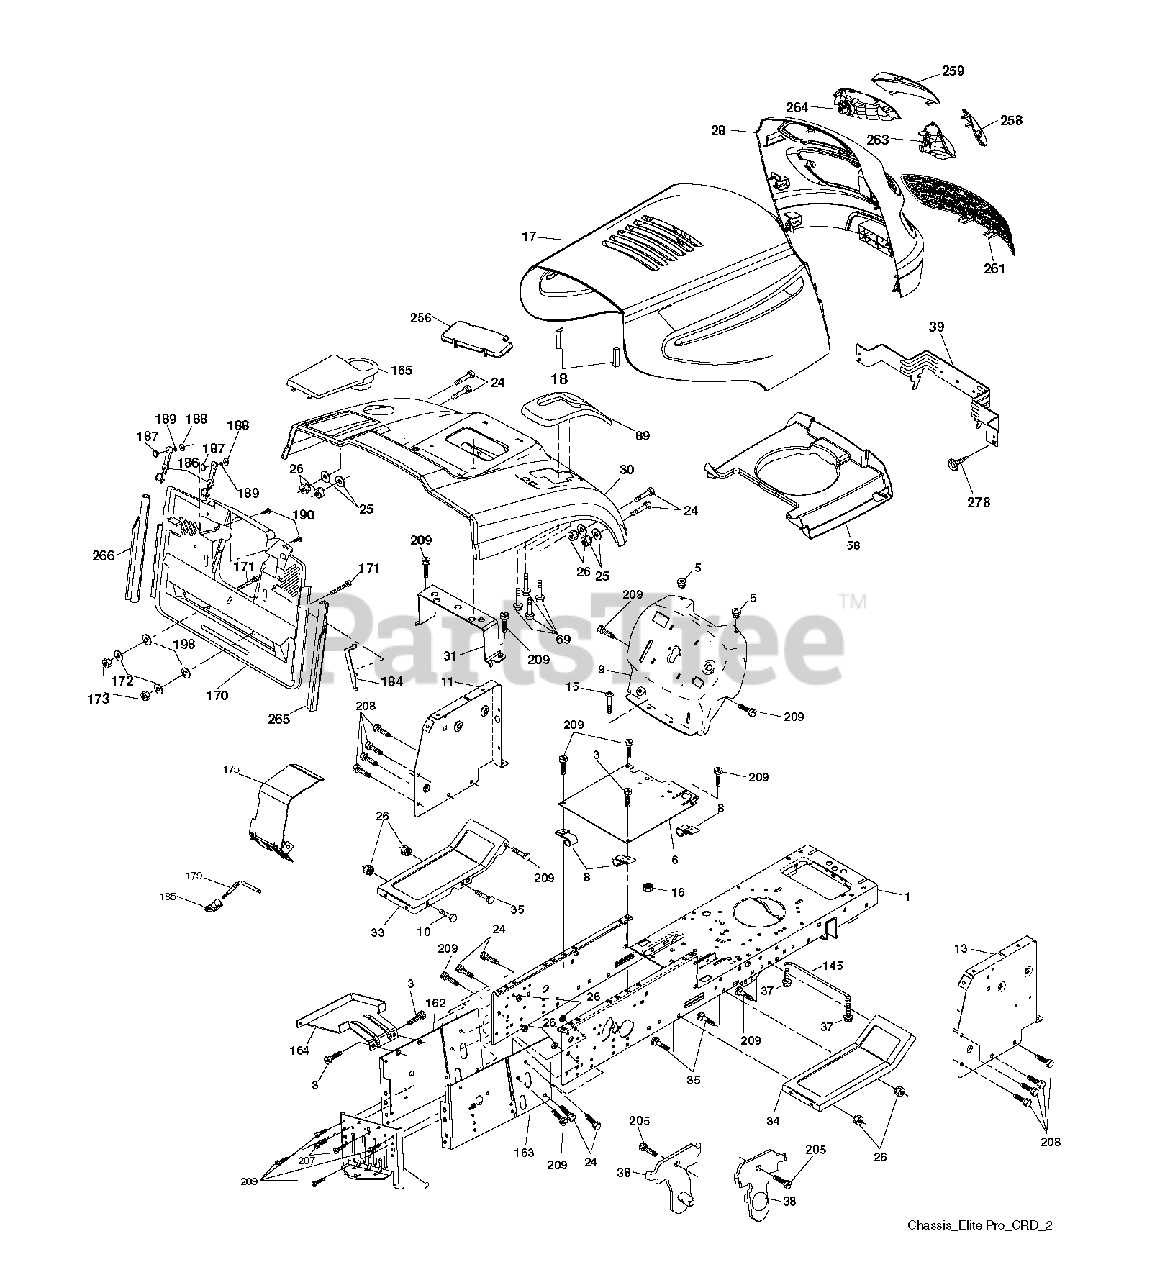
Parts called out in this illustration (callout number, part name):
1	CHASSIS
3	SCREW 3/8-16X3/4
5	BUMPER.RUBBER.HOOD
8	CLIP,INSULATOR
10	BOLT D
11	PANEL.DASH.LH.LTX
13	PANEL DASH RH
16	NUT
18	BUMPER.HOOD.LARGE.1.75"
25	WASHER
26	NUT
31	BRACKET SUPPORT FENDER
39	BRACKET PIVOT
69	SCREW.HI-LO.CONSOLE
145	ROD.PIVOT.HOOD
164	SUPPORT
171	BOLT
172	WASHER
186	LATCH ASSY
187	WELDNUT
189	LOCKWASHER
207	SCREW, 5/16-18 X 1/2
208	SCREW 3/8-16X1/2
209	SCREW, 3/8-16X3/4
263	BEZEL GRILL RH
264	BEZEL GRILL LH
278	SCREW.#10 X 0.750.BOS THREAD
